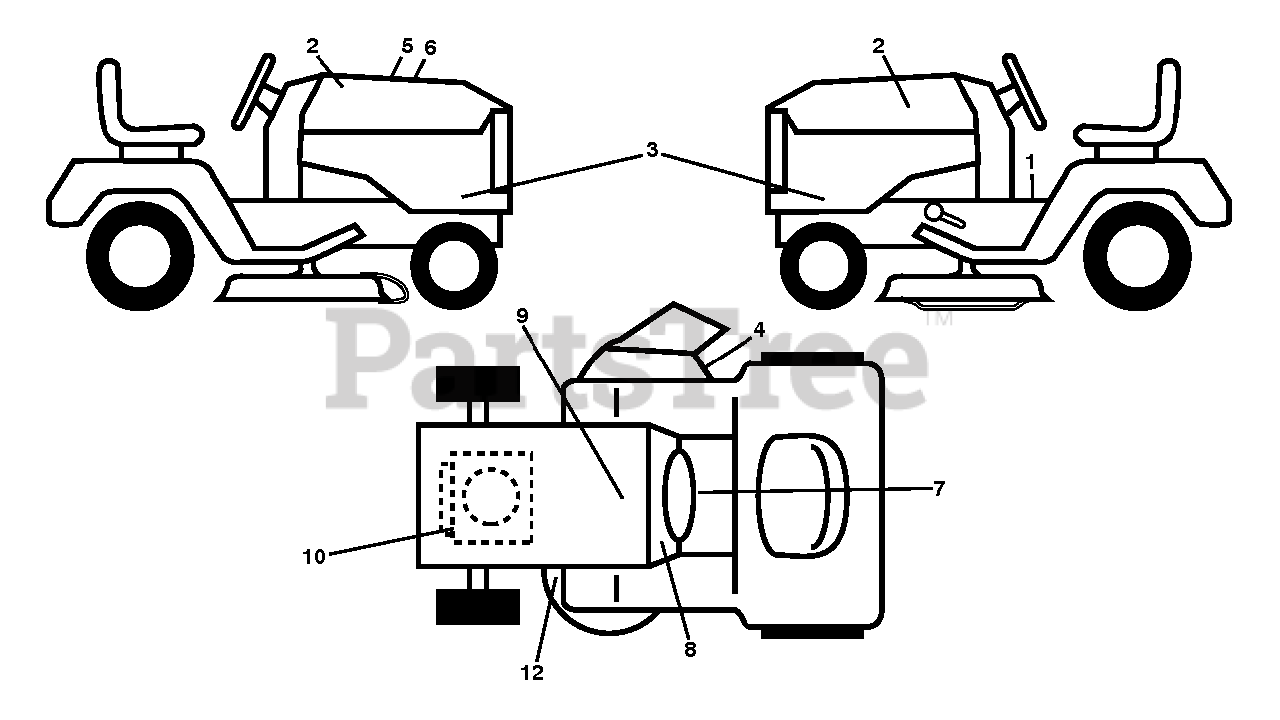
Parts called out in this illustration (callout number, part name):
1	DECAL.WARNING.2007.ENG/FR
2	DECAL.BADGE.170MM.TEXTLOGO.
3	DECAL.SDPNL.GT2.YTH20V46.SET
4	DECAL.MOWER.WARN.KEEP.HAND.AWY
5	DECAL.WARNING.CUST.RESP.E85.
7	DCL.WARNING.SPARK.IGNITION.CA
8	DECAL.SNOWFLAKE.MS498.HUSQ
9	DECAL BTRY SYMBOLS
10	DECAL DECAL.ENG.BS.ENDUR.20HP.
12	DECAL.V-BELT.SCH.42/46"MEC/ELE
